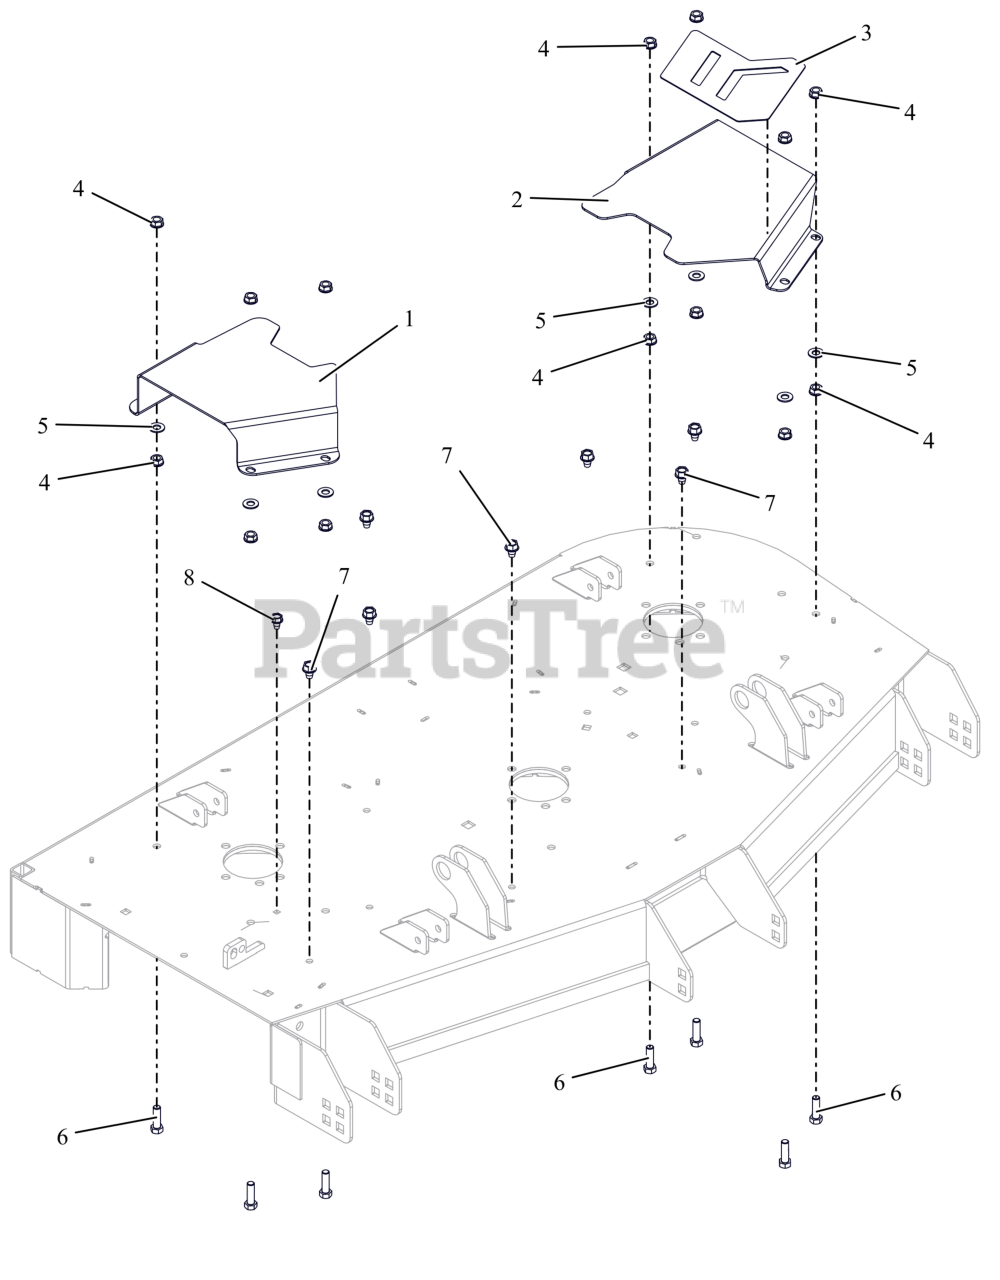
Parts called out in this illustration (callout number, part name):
1	COVER, BELT 48" RIGHT
2	COVER, BELT 48" LEFT
3	GRIP TAPE 48 BELT COVER
4	NUT, SPNLK-FLG .38-16 G5 ZCC
5	WSHR,FLT .406X.812X.065 ZCC
6	BLT, HEX .38-16X1.25 G5 ZCC
7	SCR,TAP .375-16X.50 HWH TR ZCC
8	SCR,TAP .312-18X.50 HWH TR ZCC
